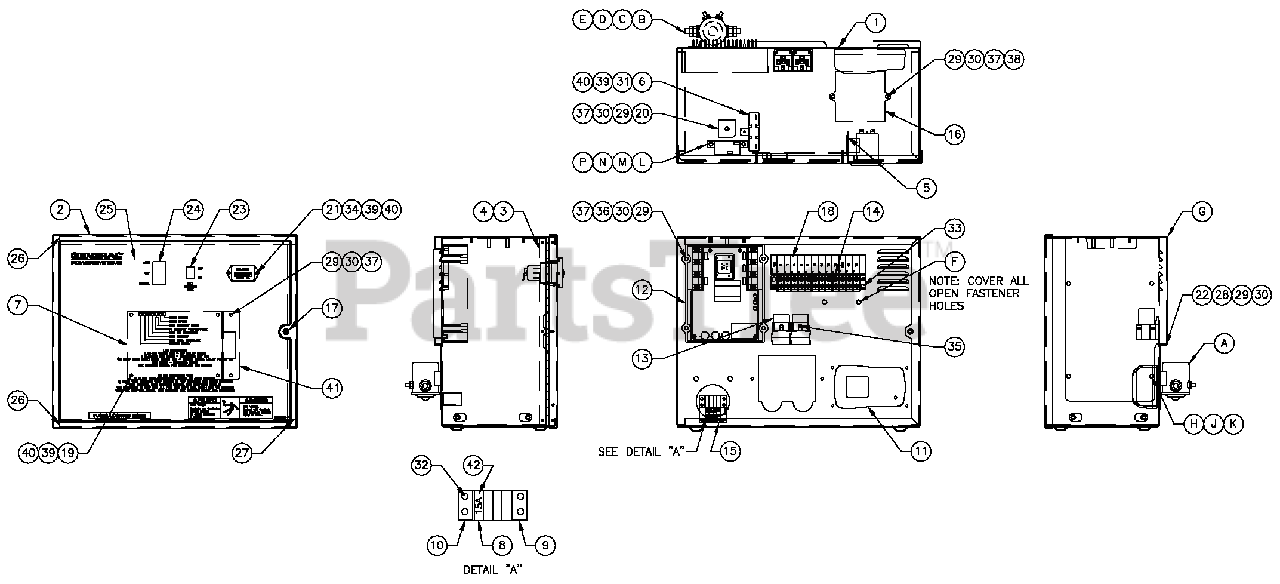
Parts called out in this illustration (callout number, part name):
1	ENCLHSBCONTROL PANEL
2	COVER CONTROL PANEL R-200B
3	HINGE CONTINUOUS H-PANEL
4	RIVET POP .125 X .275 SS
5	SCREWPPPH HI-LO#4-24X3/8
6	WASHER FLAT M3
7	ASSY PCB R200B CNTRL 1800 RPM
8	REF. HOLDERFUSEWICKMANN 178.6150
9	REF. ADPTR RH SIDE WICKMANN 178.6191
10	REF. ADPTR LH SIDE WICKMANN 178.6192
11	BATC 13.4VDC 2.5A W/4POS PLUG
12	ASSYPCB15AHIGH DROOPAVR
13	RELAY 12VDCC FORMW/DIODE
14	REF. BLOCK TERM 20A 12X 6X1100V
15	DECAL CPL CNTPNL FUSES
16	ASSY PCB BOSCH GOV DRIVER
17	M5X0.8 CAPTIVE PANEL KNLD HD
18	DECAL CPL 3.9LTB1
19	SPACER 9.5H 32 ID
20	DIO BRIDGE 25A 600V
21	HOUR METER 10-80VDC
22	PLATE HARNESS CLAMP
23	SWITCH RKRDPST 125V SPD
24	SWITCH RKR DPDT ON-OFF-ON
25	DECAL CONTROL FLEXR-200B
26	SEAL COVER 3.18X12.7X382
27	SEAL COVER 3.18X12.7X283
28	SCREW HHPMM5-0.8X 12
29	WASHER FLAT M5
30	WASHER LOCK M5
31	RES WW15R 5% 25W QK CONN
32	SCREW PHTT M3.5-0.6X10
33	SCREW PHTT M3.5-0.6X16
34	SCREWPHM M3-0.5X 1 0 BLACK
35	SCREW PHTT M4-0.7 X 10 ZYC
36	SCREW PPHMM5-0.8 X50ZNC
37	NUT HEXM5-0.8G8 YEL CHR
38	SCREW PPHM M5-0.8 X30SS
39	WASHER LOCK M3
40	NUT HEXM3-0.5G8 YEL CHR
41	SUPPORT ANGLE PCB
42	FUSE ATO TYPE 15 AMP (BLUE)
A	RELAY SOLENOID 12VDCPNLMNT
B	SCREW HHC 1/4-20X3/4 G5
C	WASHER FLAT 1/4-M6ZINC
D	WASHER LOCK M6-1/4
E	NUT HEX 1/4-20STEEL
F	SEAL WEATHER .45"DIA
G	COVER CONTROL PANEL SIDE
H	SCREW PPHM M5-0.8 X12ZNC
J	WASHER LOCK M5
K	WASHER FLAT M5
L	CB 5.5AX1PAUTO
M	WASHER FLAT M3
N	WASHER LOCK M3
P	NUT HEXM3-0.5G8 YEL CHR
